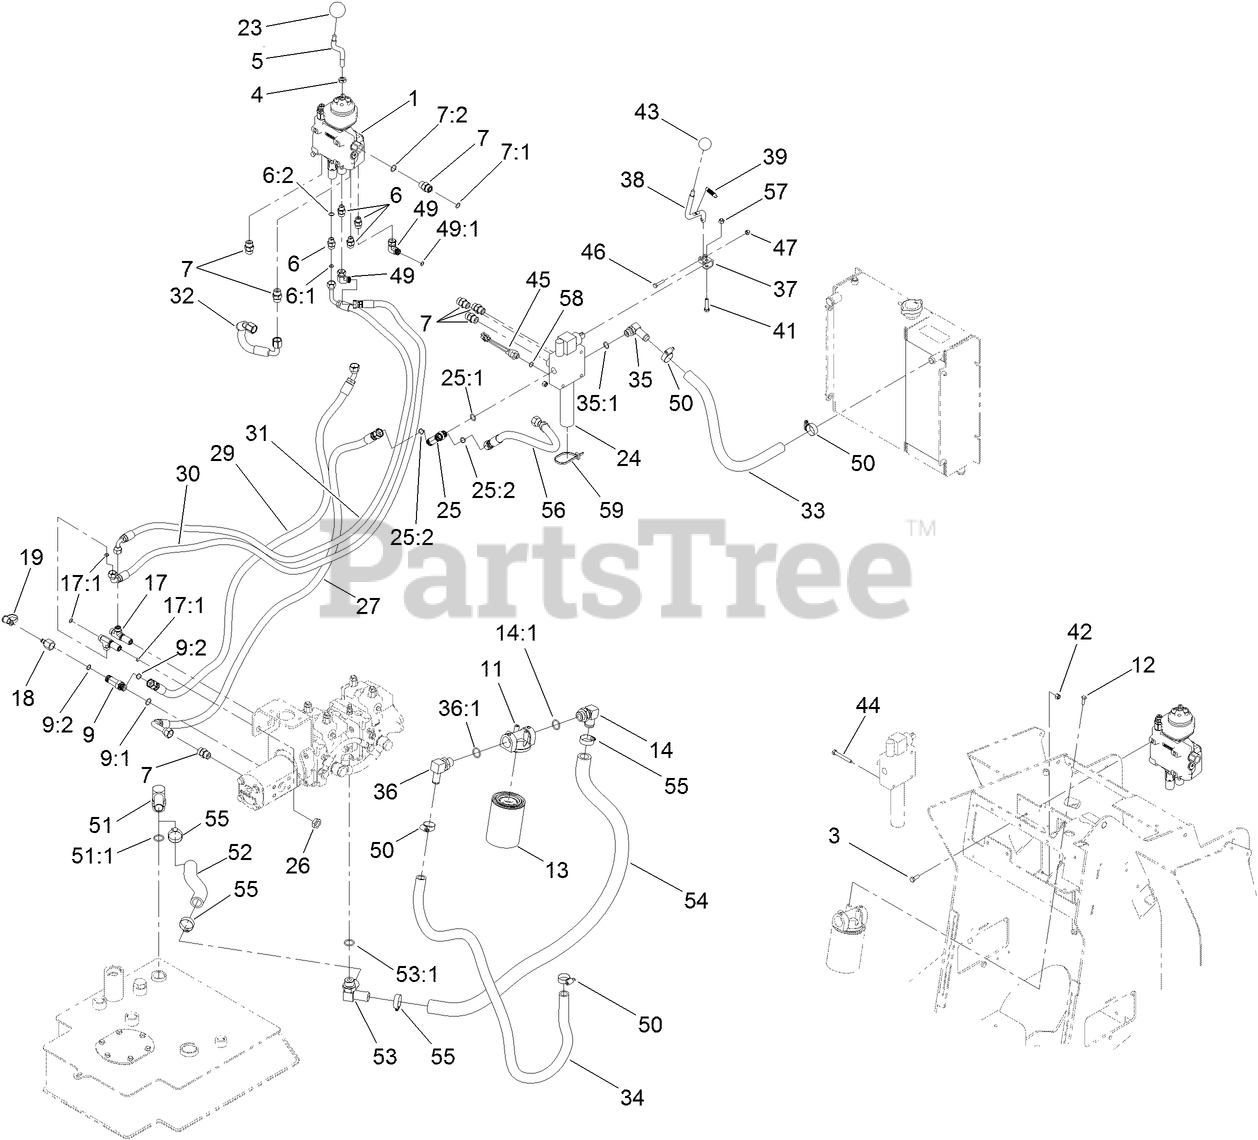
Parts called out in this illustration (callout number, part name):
1	2 SPOOL VALVE ASM
3	SCREW-HH
5	SHAFT-HANDLE
6	FITTING-STRAIGHT
6:1	O-RING
6:2	O-RING
7	FITTING-STRAIGHT
7:1	O-RING
7:2	O-RING
9	FITTING-TEE
9:1	O-RING
9:2	O-RING
11	HEAD-FILTER
12	SCREW-HH
13	FILTER-OIL
14	FITTING-HYD, 90 DEG
14:1	O-RING
17	FITTING-TEE, BULKHEAD
17:1	O-RING
18	FITTING
19	CAP-DUST
24	VALVE-AUXILIARY
25	FITTING-HYD, TEE
25:1	O-RING
25:2	O-RING
26	NUT-LOCK
27	HOSE-HYD
29	HOSE-HYD
30	HOSE-HYD
31	HOSE-HYD
32	HOSE-RETURN
33	HOSE-RETURN
34	HOSE-RETURN
35	FITTING-ELB 90
35:1	O-RING
36	FITTING-ELB 90
36:1	O-RING
37	BRACKET-AUXILIARY
38	ROD-AUXILIARY
39	SPRING-EXTENSION
41	SCREW-HH
42	NUT-LOCK, NI
44	SCREW-HH
45	SWITCH-BALL
46	SCREW-HH
47	NUT-LOCK, NI
49	FITTING-HYD, 90 DEG
49:1	O-RING
50	CLAMP-HOSE
51	FITTING-HYD, 90 DEG
51:1	O-RING
52	HOSE-SUCTION
53	CONNECTOR
53:1	O-RING
54	HOSE-RETURN
55	CLAMP-HOSE
56	HOSE-HYD
57	NUT-LOCK, NI
58	O-RING
59	TIE-CABLE
